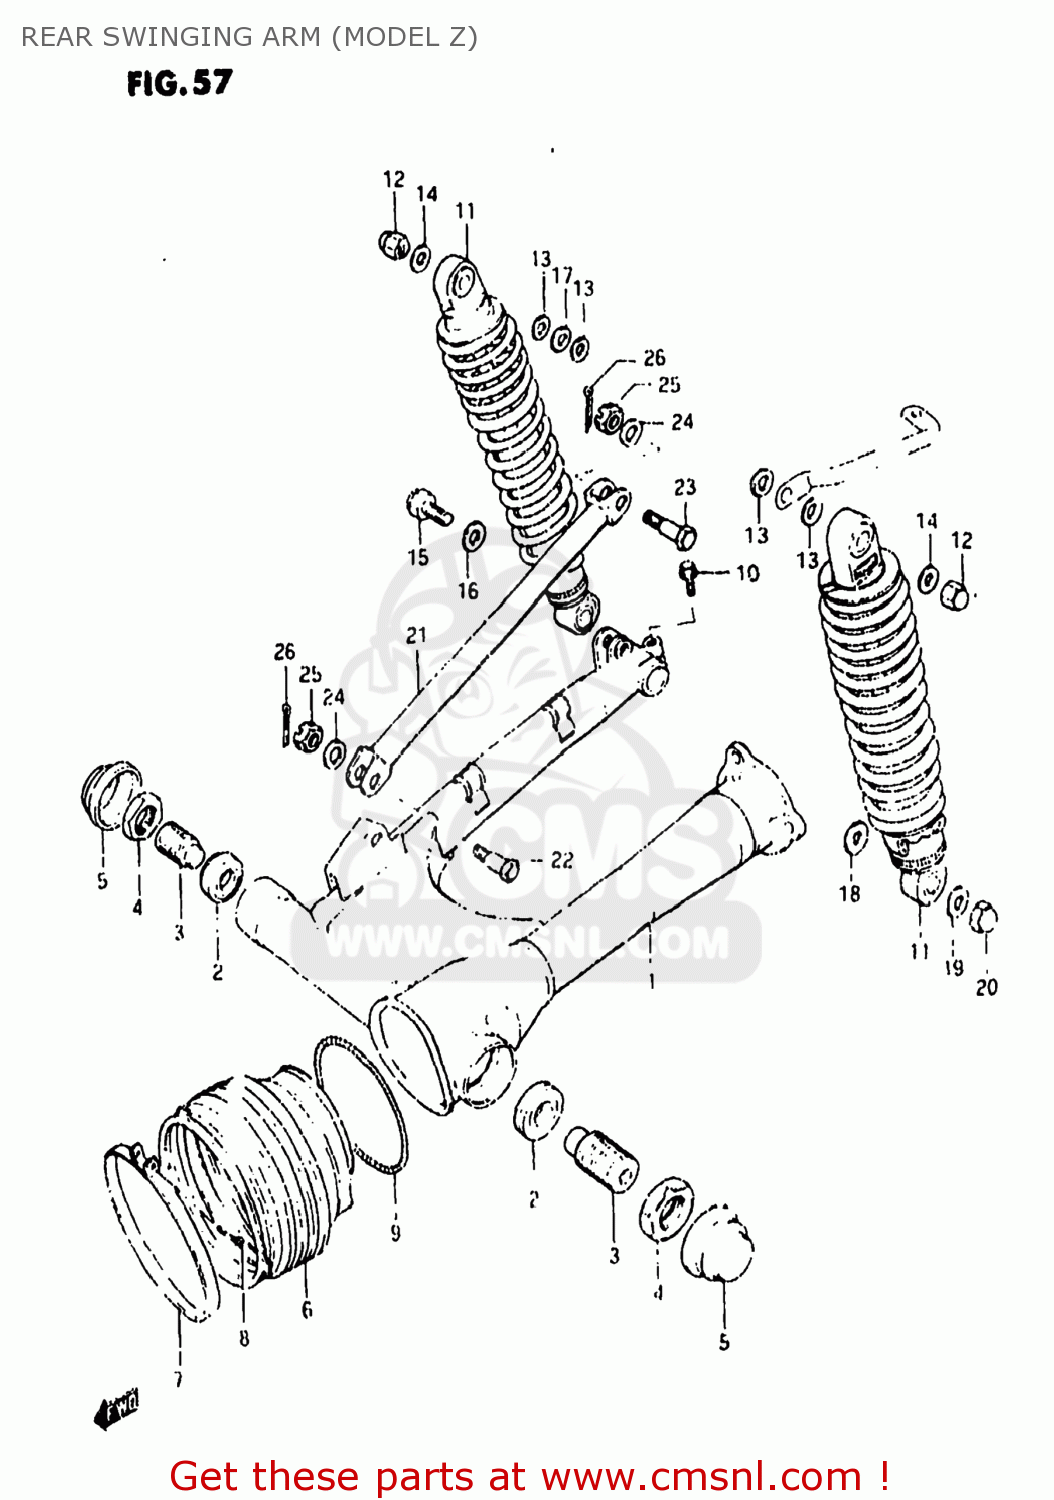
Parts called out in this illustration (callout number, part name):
1	SWING ARM SET,REAR (B
2	BEARING(17X40X13.25)
3	BOLT,REAR SWING ARM PIVOT
4	NUT
5	CAP,REAR SWING ARM PIVOT
6	BOOT,PROPELLER SHAFT
7	CLAMP
8	SCREW 4X25
9	SPRING,PROPELLER SHAFT
10	BOLT
11	ABSORBER ASSEMBLY,REAR SHOCK
12	NUT
13	WASHER
14	WASHER
15	BOLT 12X33
16	WASHER (12.5X24X1.6)
17	WASHER (12.5X24X3.2)
18	WASHER
19	WASHER
20	NUT, LOWER LH
21	TORQUE LINK,REAR
22	BOLT
23	BOLT(10X39)
24	WASHER
25	NUT
26	PIN 20X20
